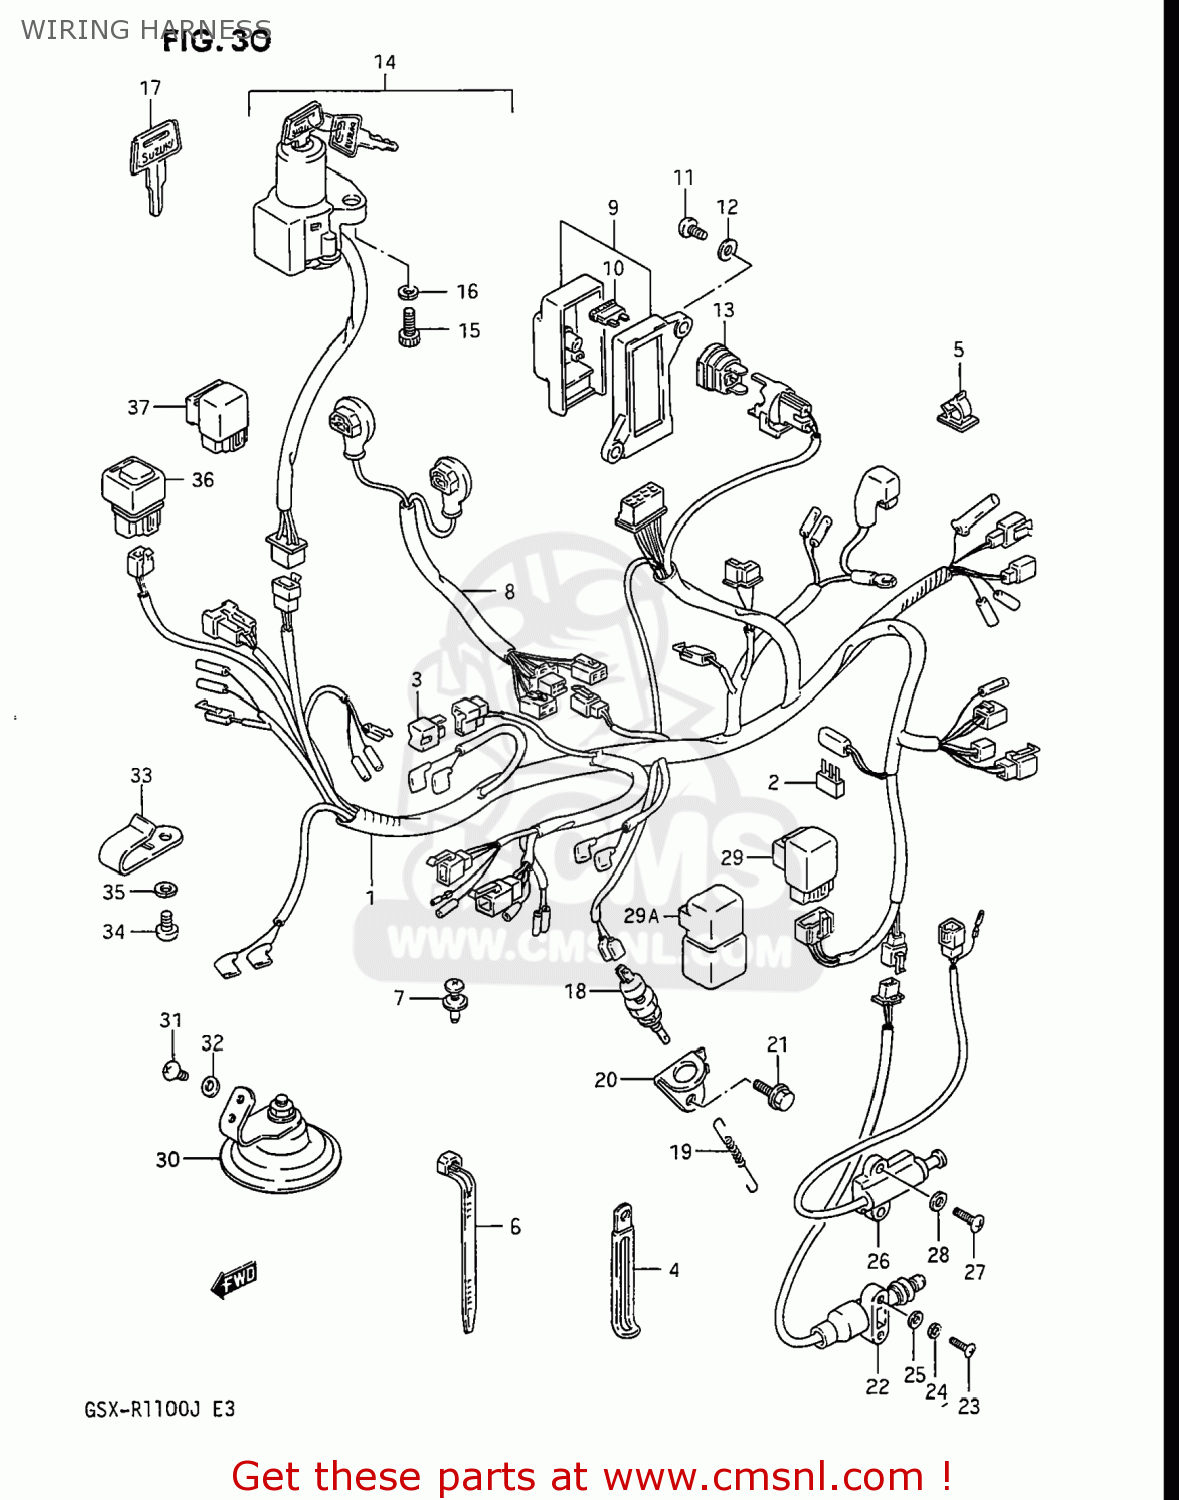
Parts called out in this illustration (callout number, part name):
1	HARNESS,WIRING
2	DIODE(STANLEY DE8804)
3	RECTIFIER ASSY
4	CLAMP
5	CLAMP
6	CLAMP(L:125)
7	CLIP
8	WIRE
9	BOX ASSEMBLY,FUSE
10	FUSE(10A)
11	SCREW 6X12
12	WASHER
13	BREAKER ASSY,CIRCUT
14	SWITCH ASSY,IGNITION
15	BOLT
16	WASHER,LOCK
17	KEY,BLANK
18	SWITCH ASSY,STOP LAMP
19	SPRING
20	BRACKET,STOP LAMP SWITCH
21	BOLT
22	SWITCH ASSY,SIDE STAND WARN
23	SCREW 5X20
24	WASHER,LOCK
25	WASHER,5MM
26	SWITCH ASSEMBLY,SIDE STAND
27	SCREW
28	WASHER
29	RELAY ASSEMBLY
29A	RELAY ASSEMBLY
30	HORN ASSEMBLY
31	SCREW
32	WASHER
33	CLAMP,HANDLE SWITCH LEVER
34	SCREW
35	WASHER,LOCK
36	RELAY, ANTINOSE DIVE FORK
37	RELAY ASSY,HEADLAMP
